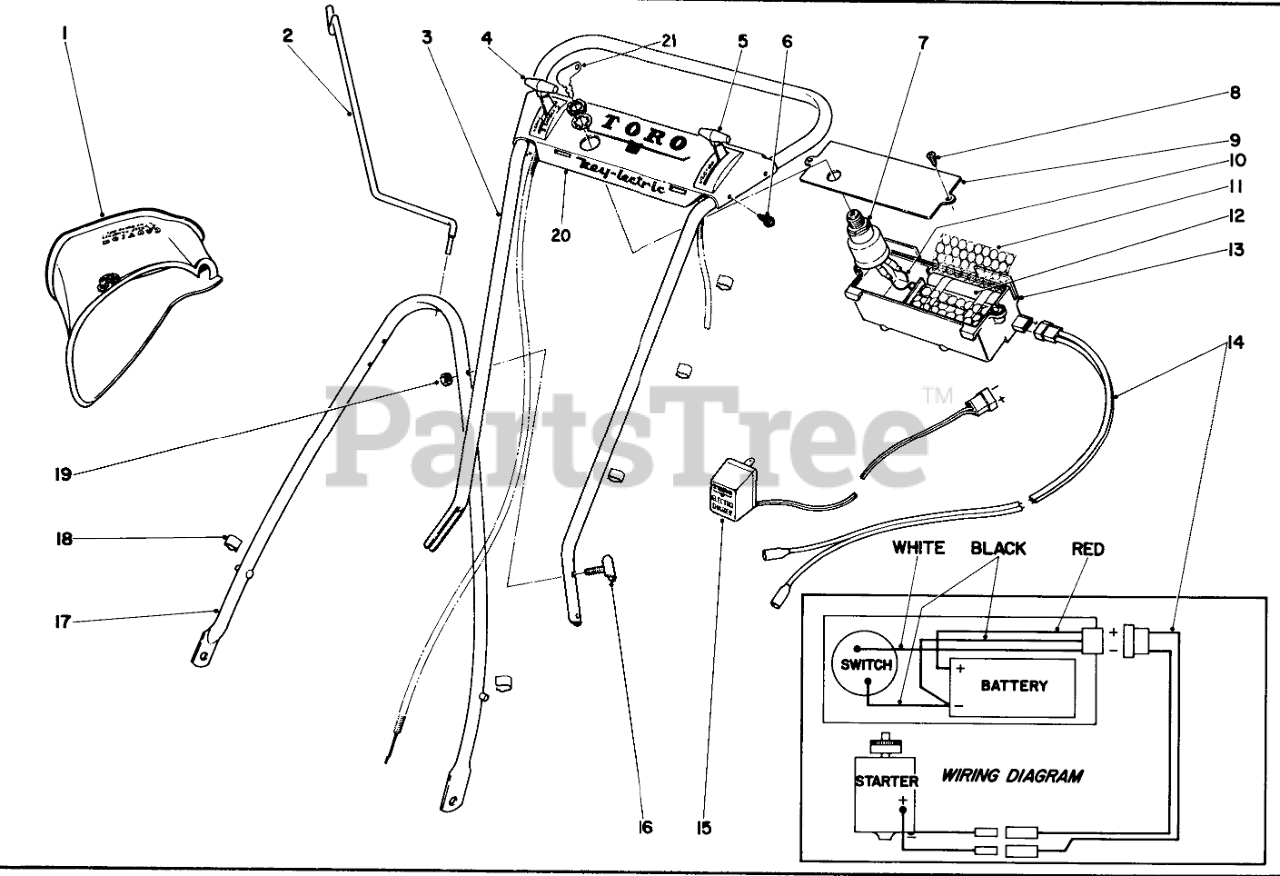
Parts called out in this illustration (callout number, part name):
1	Attachment Bag
2	GRASS BAG HANGER
3	Handle-Upper
4	Throttle Control
5	Traction Control
6	SCREW-HWHTF
7	Starter Switch
8	Self Tapping Screw
9	Cover Battery Pack
10	Lead Wire
11	Spacer-Battery
12	Battery & Wire Assembly
13	Container Battery Pack
14	Wiring Harness
15	Battery Charger
17	Handle-Lower
18	CONTROL WIRE CLIP
19	Nut
20	Escutcheon Plate
